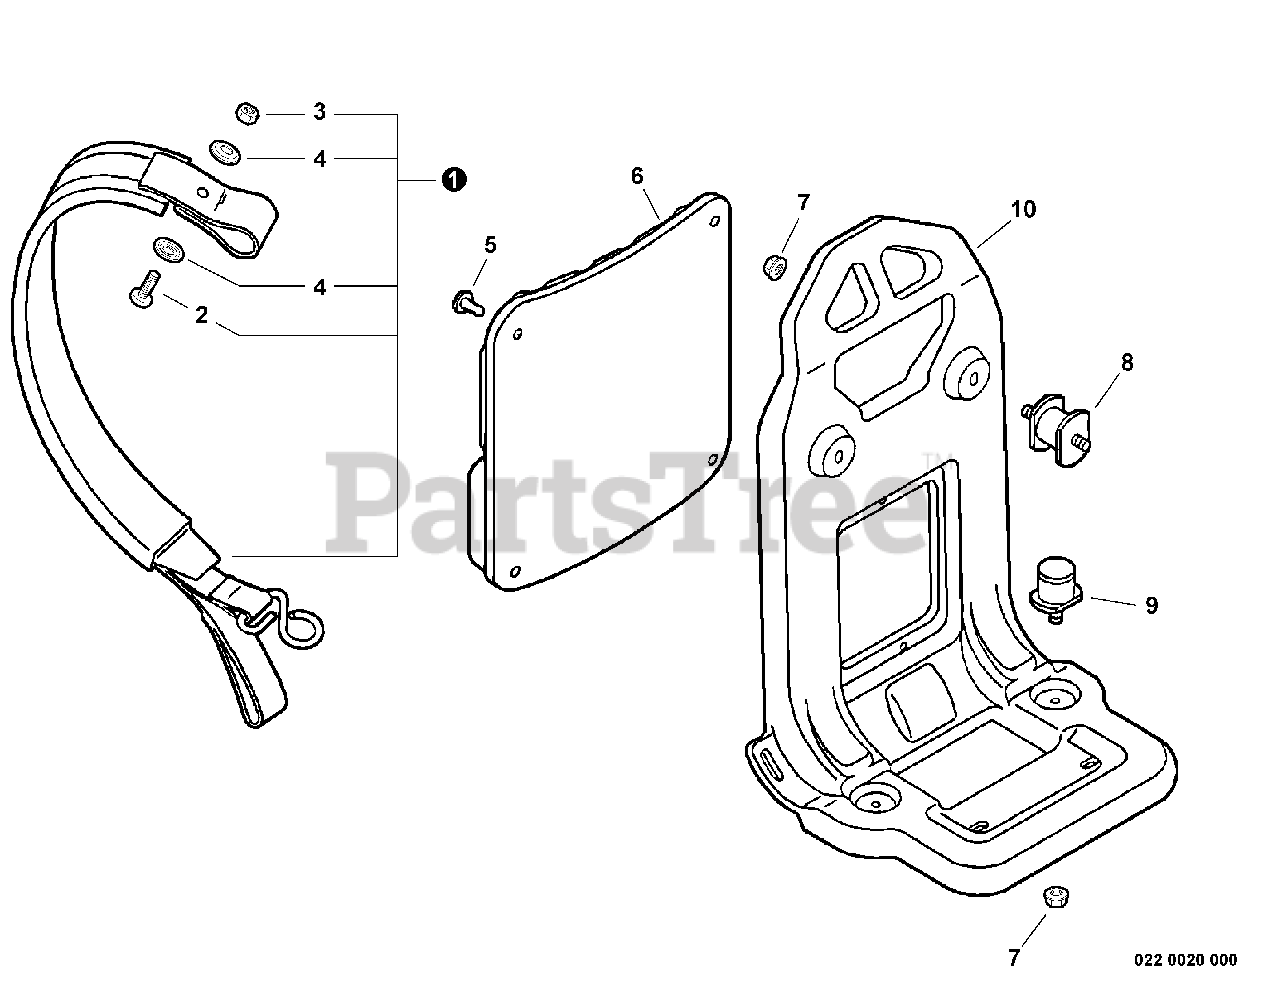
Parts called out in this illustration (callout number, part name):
1	STRAP ASSY
2	SCREW - 5X16
3	LOCKNUT - 5
6	CUSHION, BACKPACK
10	FRAME, BACKPACK
